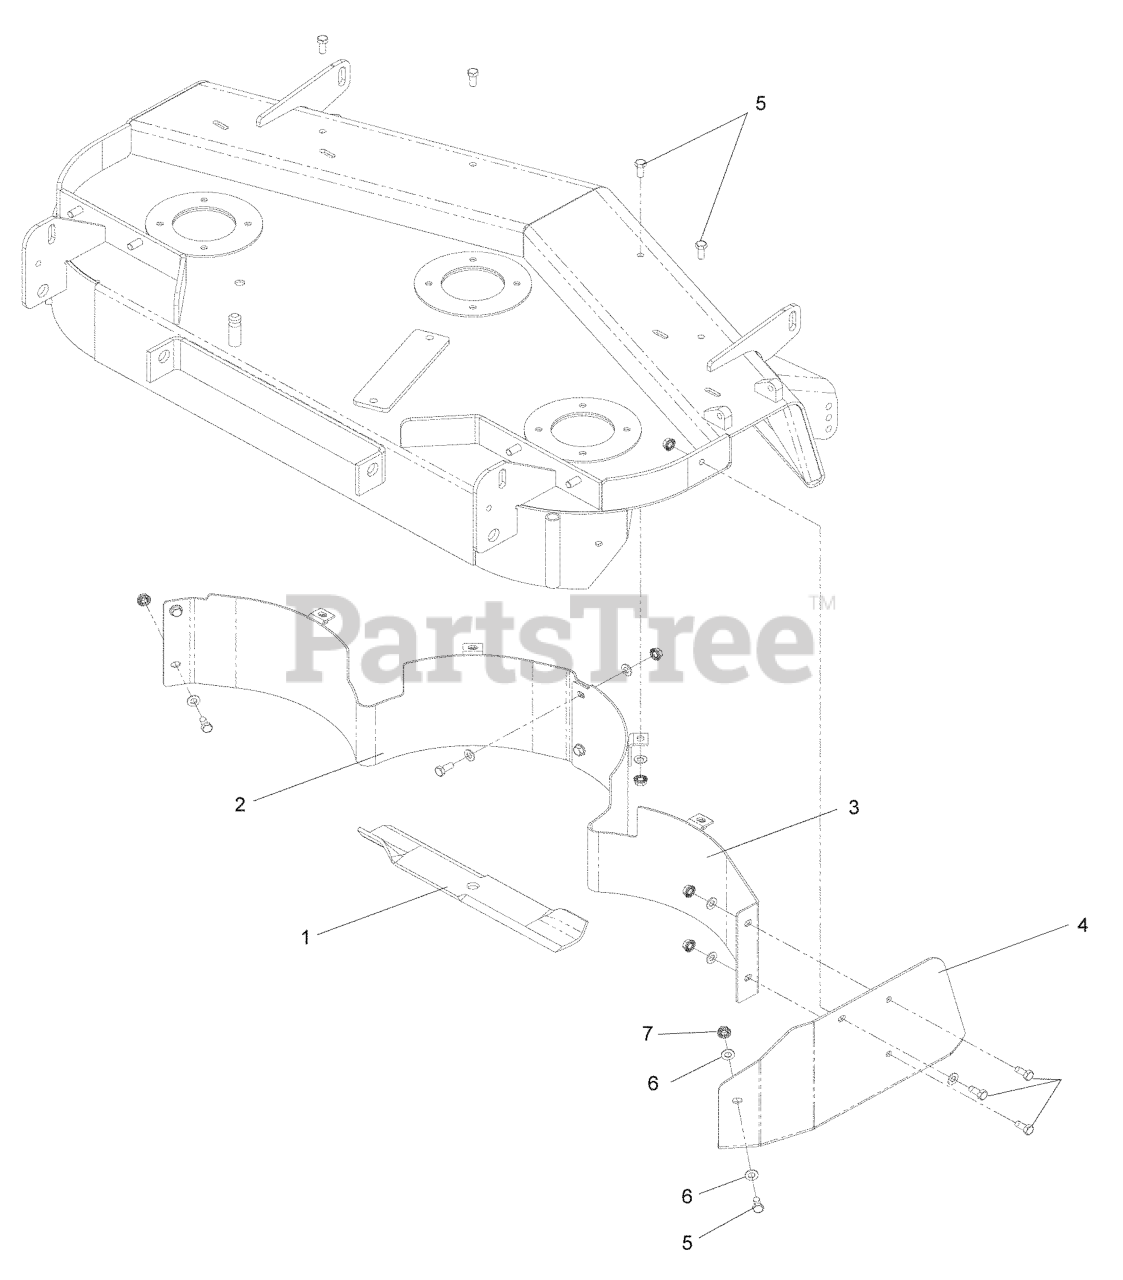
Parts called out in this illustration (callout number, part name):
1	BLADE MULCH 14-7/8"
2	MULCH BAFFLE, LEFT, 42
3	BAFFLE WLDMT, 42" R.H. MULCH
4	MULCH CAP 42"
5	HCS 5/16C X 3/4
6	FLAT WASHER 5/16 SAE
7	NUT 5/16C WHIZ
